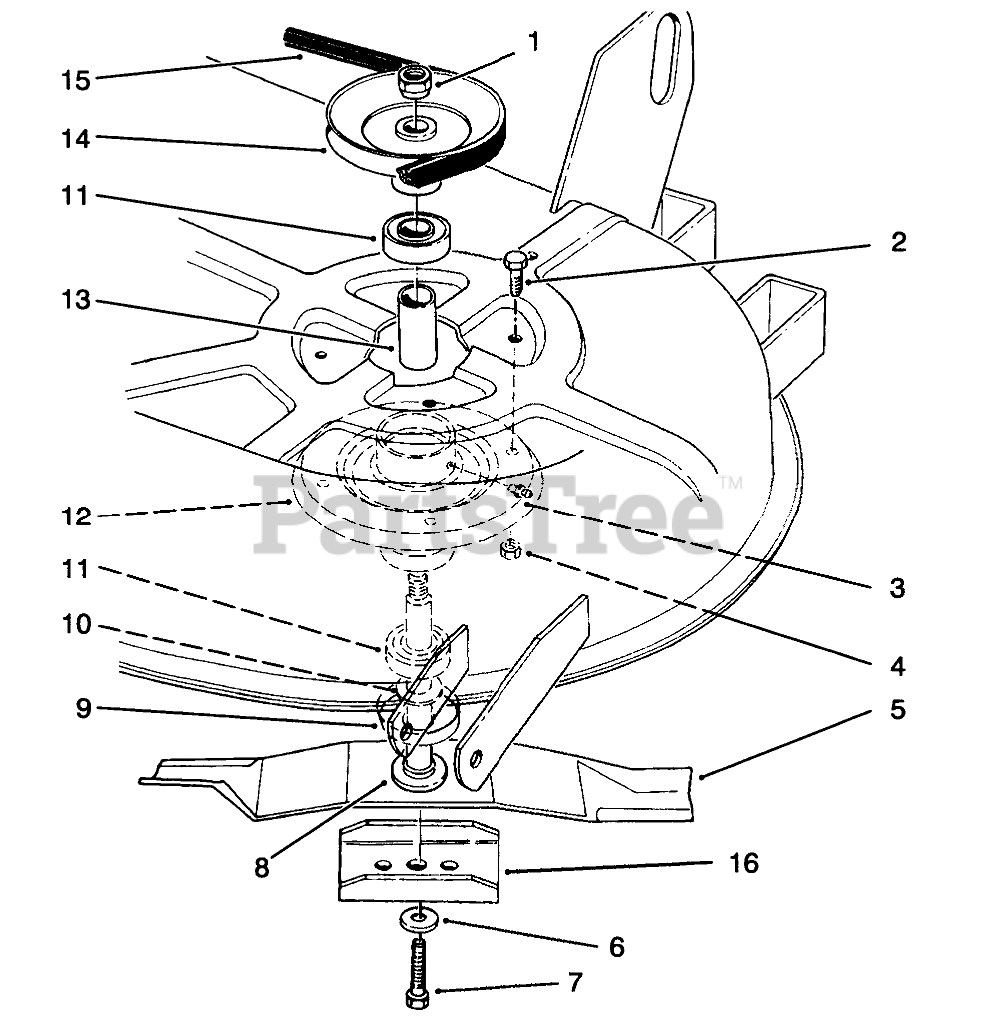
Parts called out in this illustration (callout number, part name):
1	Nut
2	SCREW-HH
3	ZERK FITTING
4	NUT-LOCK, NI
5	Blade
6	WASHER-BELLEVILLE
7	SCREW-HH
8	SHAFT-SPINDLE
9	SHIELD-BEARING
10	SPACER-HARDNED
11	BEARING-BALL
12	HOUSING-SPINDLE (BLACK)
13	SPACER
14	PULLEY
15	V-BELT
16	STIFFENER-BLADE
